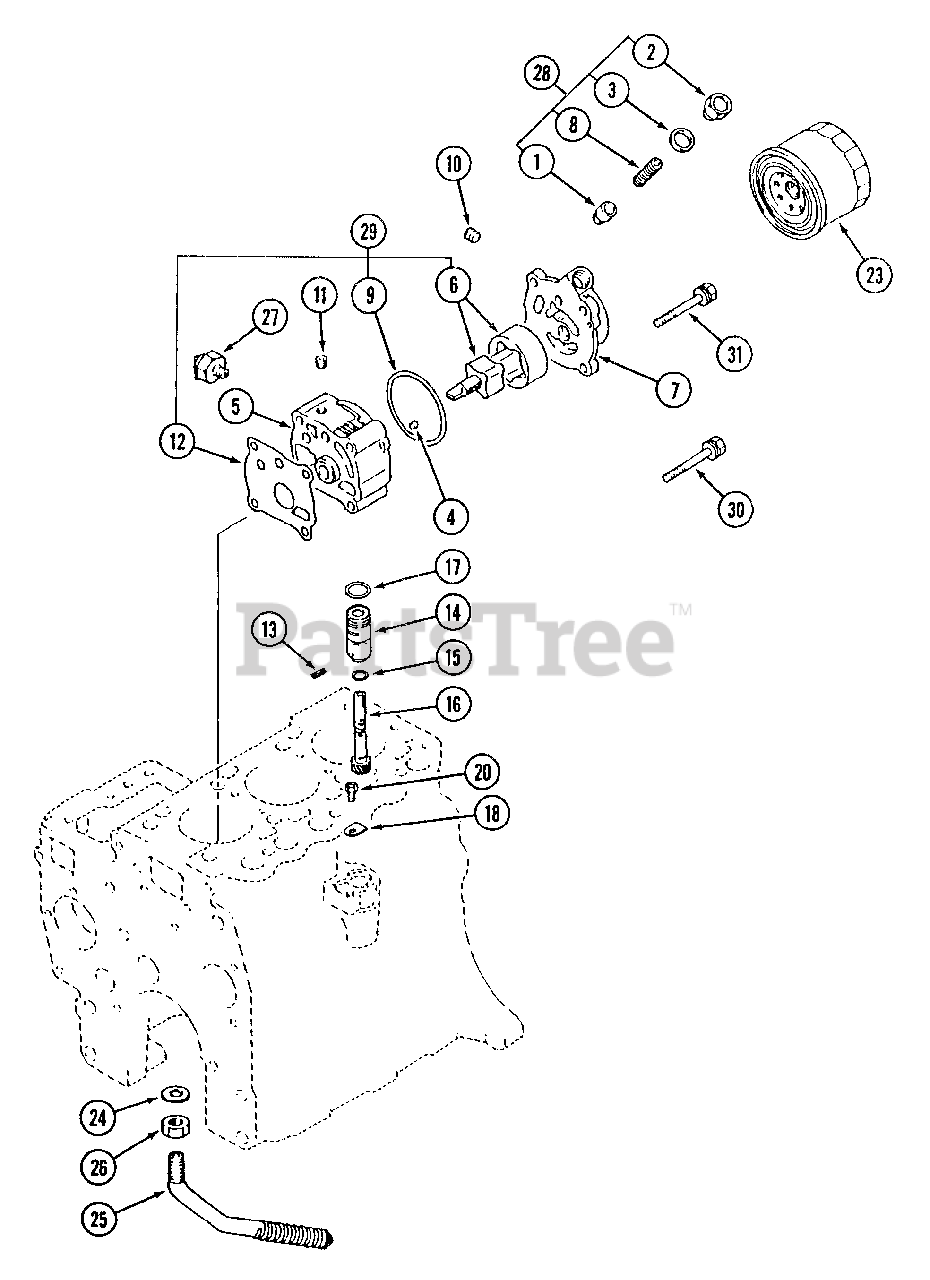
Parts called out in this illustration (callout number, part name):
1	Plunger, Relief
2	Plug, Relief
4	Pin, Dowel
5	Body, Oil Pump
6	Rotor Ass'y.
7	Cover, Oil Pump
8	Spring, Relief
12	Gasket, Oil Pump
13	Pin, Spring
14	Sleeve, Gear
16	Gear, Driven
17	O-Ring
18	Plate, Locking
20	Bolt,
23	Oil Filter Ass'y.
24	Washer, Seal
25	Oil Screen Ass'y.
27	Oil Pressure Switch Ass'y.
28	Service Kit, Relief Valve
29	Service Kit, Rotor
30	Bolt,
31	Bolt,
